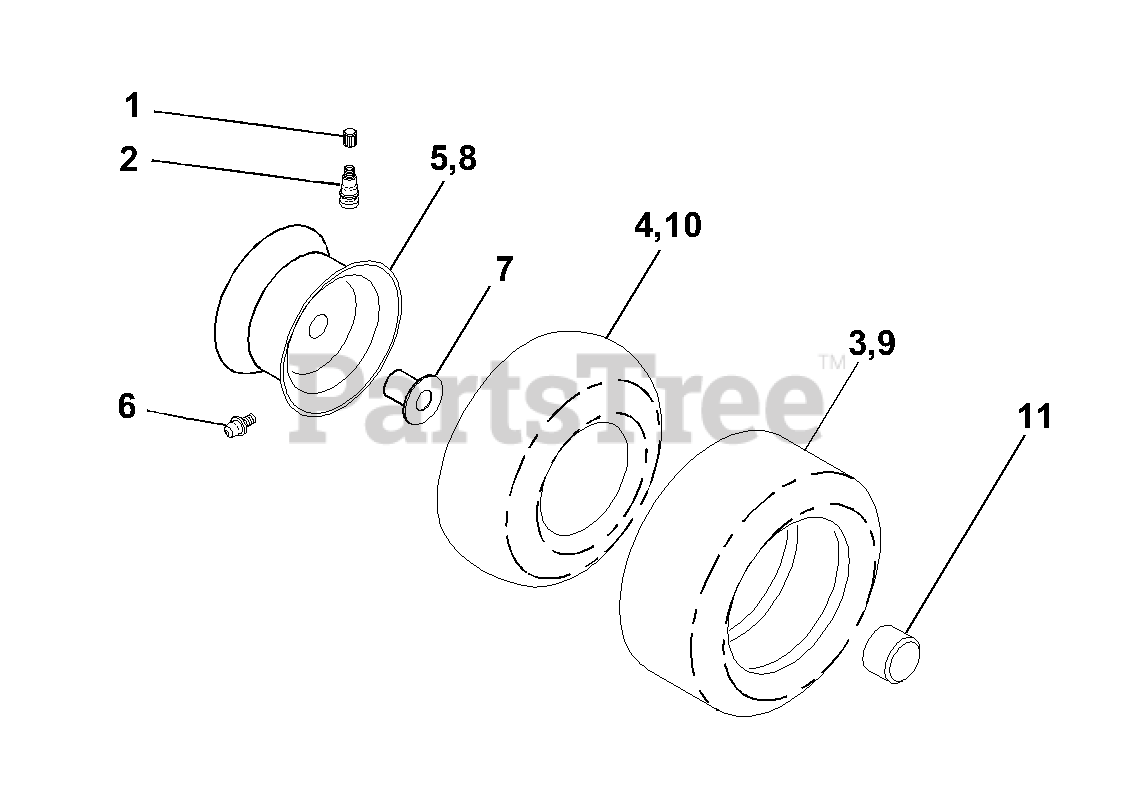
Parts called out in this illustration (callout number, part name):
1	Cap Value Tire
2	Stem Value
3	Tire F Ts 15 X 6 0 - 6 Service
4	Tube Inner Front #35060
5	Rim Asm 6" front White Service
6	Fitting Grease
7	Bearing Flange
8	Rim Asm 8" rear White Service
9	Tire R Ts 20 x 8-8 Service
10	Tube Rear 9 5 X 8 Service
11	Cap Axle Blk 1 50 X 1 00
